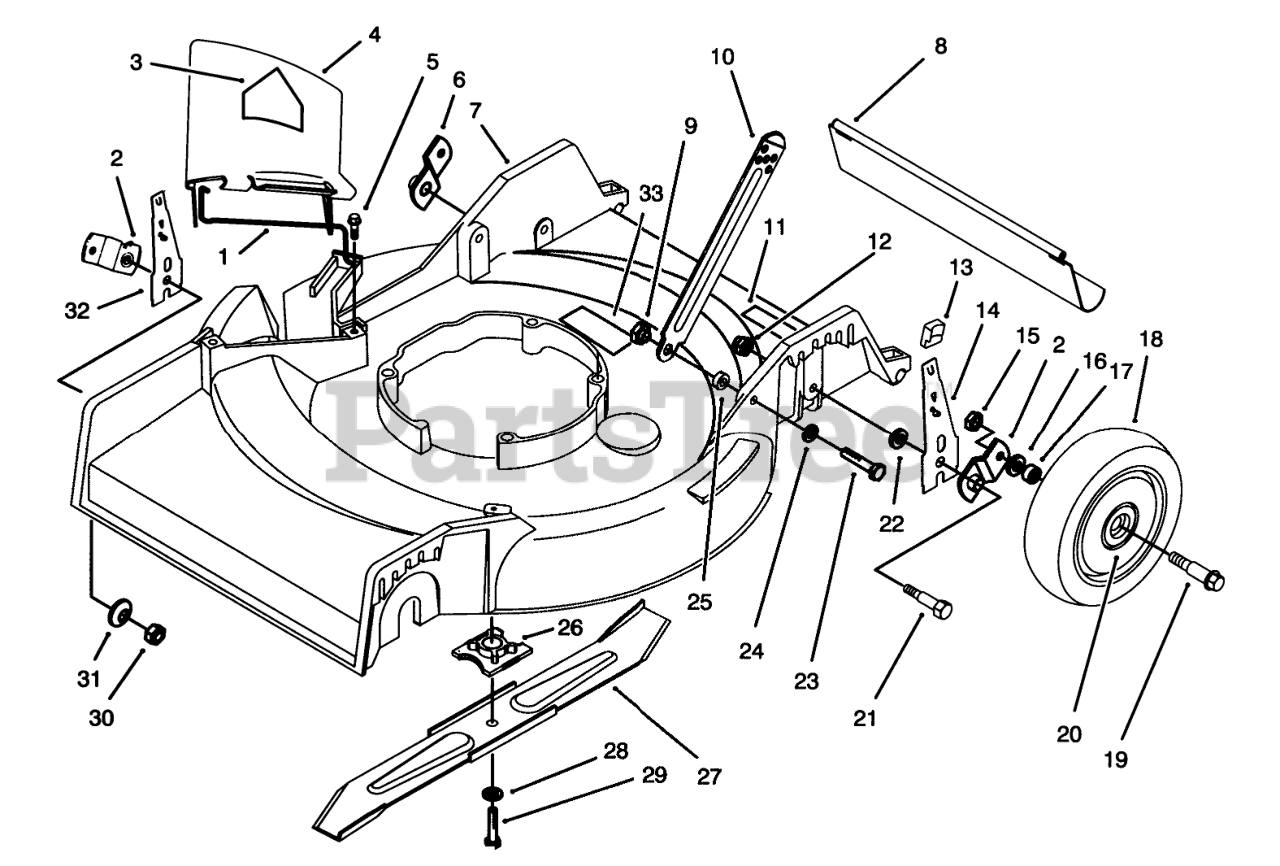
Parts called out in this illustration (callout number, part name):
1	SPRING HINGE
2	Pivot Arm
3	DECAL-DANGER
4	Deflector (Incl. Ref. #1 & 3)
5	SCREW-HWH
6	Pivot Arm
7	Housing Assembly (Incl. Ref. #11 & 33)
8	SHIELD - TRAILING
9	HANDLE PIVOT NUT
10	HANDLE LATCH
11	DECAL-WARNING
12	HANDLE PIVOT NUT
13	KNOB-ARM
14	REAR SPRING ARM ASM
15	NUT-LOCK
16	WASHER
17	WHEEL SPACER
18	Wheel & Tire Assembly (Incl. Ref. #20)
19	WHEEL BOLT
20	BUSHING
21	5/16-18 PIVOT SCREW
22	PIVOT WASHER
23	SCREW-HH
24	WASHER-LOCK
25	SPACER
26	BLADE RETAINER
27	Blade
28	WASHER-LOCK
29	SCREW-HH
30	NUT-LOCK, NI
31	WASHER-BELLEVILLE
32	RH FRONT SPRING ARM ASM
33	DECAL-INSTRUCTION, SAFETY
